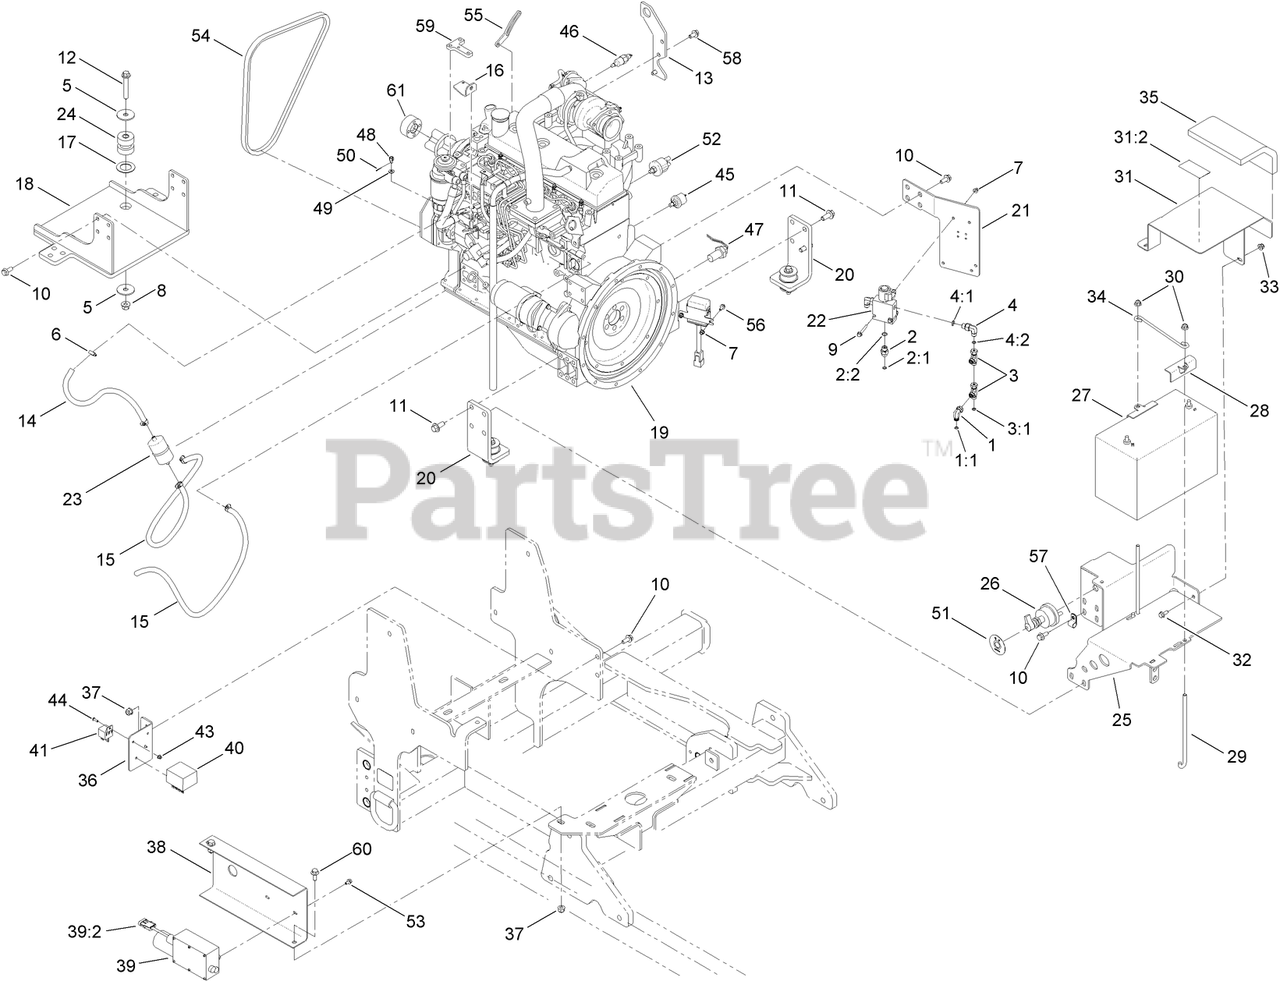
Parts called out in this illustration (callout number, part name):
1	FITTING-ADAPTOR
1:1	O-RING
2	FITTING-STRAIGHT
2:1	O-RING
2:2	O-RING
3	FITTING-HYD
3:1	O-Ring
4	FITTING-ELBOW 90
4:1	O-RING
4:2	O-RING
5	WASHER-FLAT
6	CLAMP-WORM
7	NUT-FLANGE, NI
8	NUT-LOCK, HHF
9	SCREW-HHF
10	SCREW-HHF
11	SCREW-HHF
12	SCREW-HHF
13	PLATE-HOIST POINT
14	HOSE-FUEL
15	HOSE-FUEL
16	BRACKET-THROTTLE
17	SPACER-ISOLATOR
18	MOUNT-ENGINE AND RADIATOR
19	Engine ASM
20	BRACKET-MOUNT, ENGINE
21	PLATE-MOUNT
22	VALVE-SOLENOID
23	FILTER-INLINE FUEL
24	ISOLATOR-MOUNTING, UNIVERSAL
25	BRACKET-MOUNT, BATTERY
26	SWITCH-BATTERY (1000 AMP)
28	ANGLE-HOLDDOWN, BATTERY
29	BOLT-HOLDDOWN, BATTERY
30	NUT-HF, NI
31	BATTERY SHIELD ASM
31:2	DECAL-WARNING, BATTERY
32	SCREW-HHF
33	NUT-LOCK, HHF
34	BRACKET-HOLDDOWN, BATTERY
35	SHIELD-HEAT
36	BRACKET-MOUNTING, RELAY
37	NUT-LOCK, NI
38	BRACKET-THROTTLE
39	ACTUATOR-THROTTLE
39:2	CONNECTOR
40	RELAY-CONTROL, ENGINE
41	RELAY-POWER
43	NUT-HF
44	SCREW-HSBH
45	SENSOR-PRESSURE, OIL
46	SENSOR-COOLANT
47	SENSOR-RPM, MAG PICKUP
48	PIVOT-THROTTLE
49	WASHER-FLAT
50	PIN-COTTER
51	FACEPLATE-BATTERY, ON/OFF
52	SENSOR-PRESSURE, OIL
53	SCREW-HHF
54	BELT-V
55	BRACKET-ALTERNATOR
56	SCREW-HHF
57	R-CLAMP
58	SCREW-HHF
59	PLATE-MOUNT, FILTER
60	SCREW-HHF
61	SPACER-FAN
